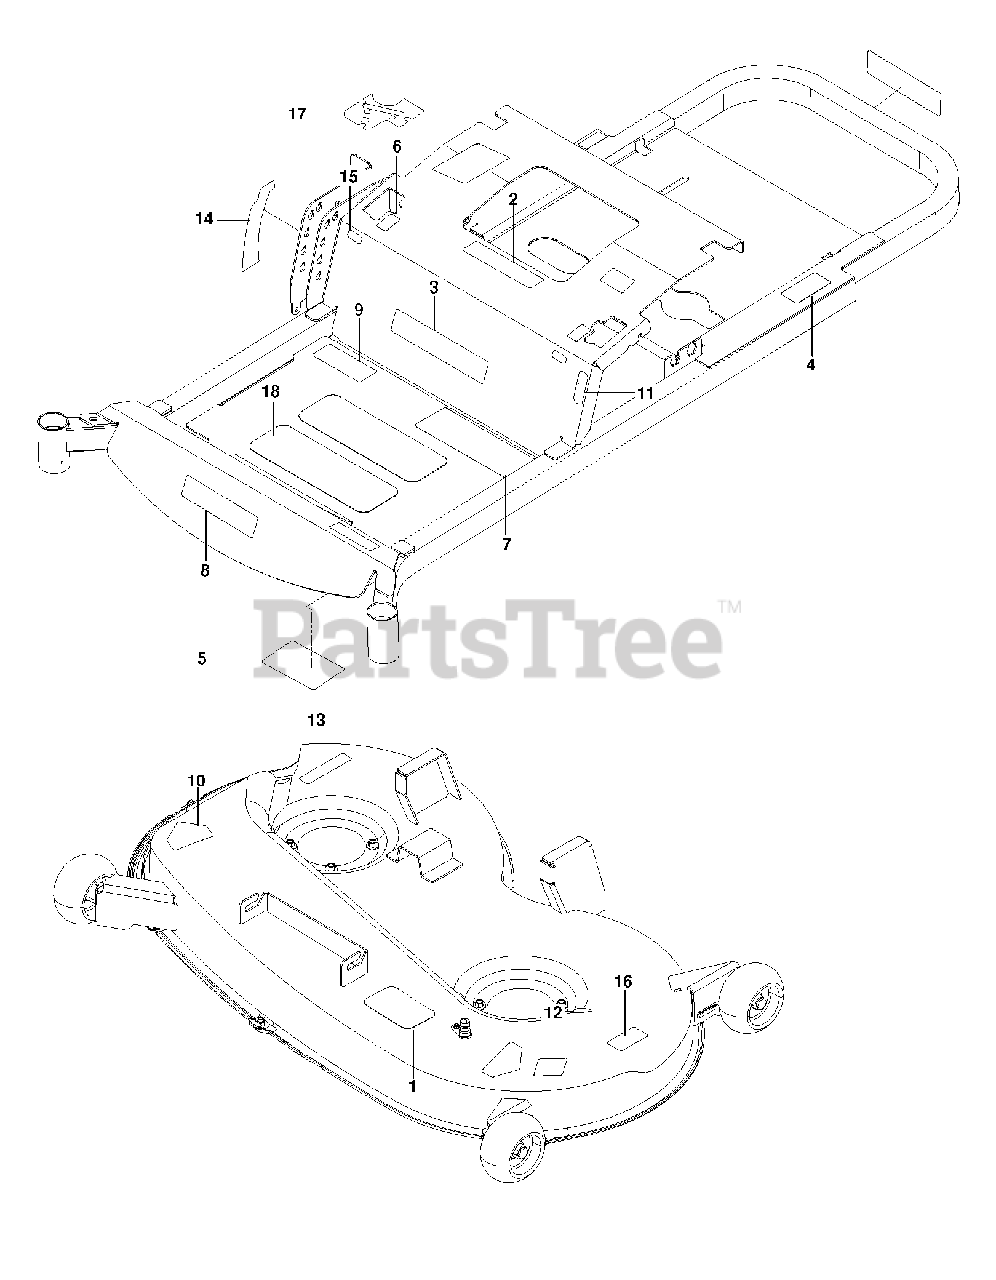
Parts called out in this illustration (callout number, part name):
1	DECAL, BELT ROUTING
3	DECAL, SPEEDZTR, 8"
4	DECAL, DO NOT MOUNT
5	DECAL, SERVICE
6	DECAL, MOTION CONTROL
7	DECAL, SAFETY WARNING
10	DECAL, CPSC
11	DECAL, PARK BRAKE
12	DECAL, EURO SEVERING
14	DECAL, HEIGHT
15	DECAL, TRACKING
16	DECAL, 46" WHITE
17	DECAL, CONTROLS PANEL, DIX
18	ANTI-SKID PAD
